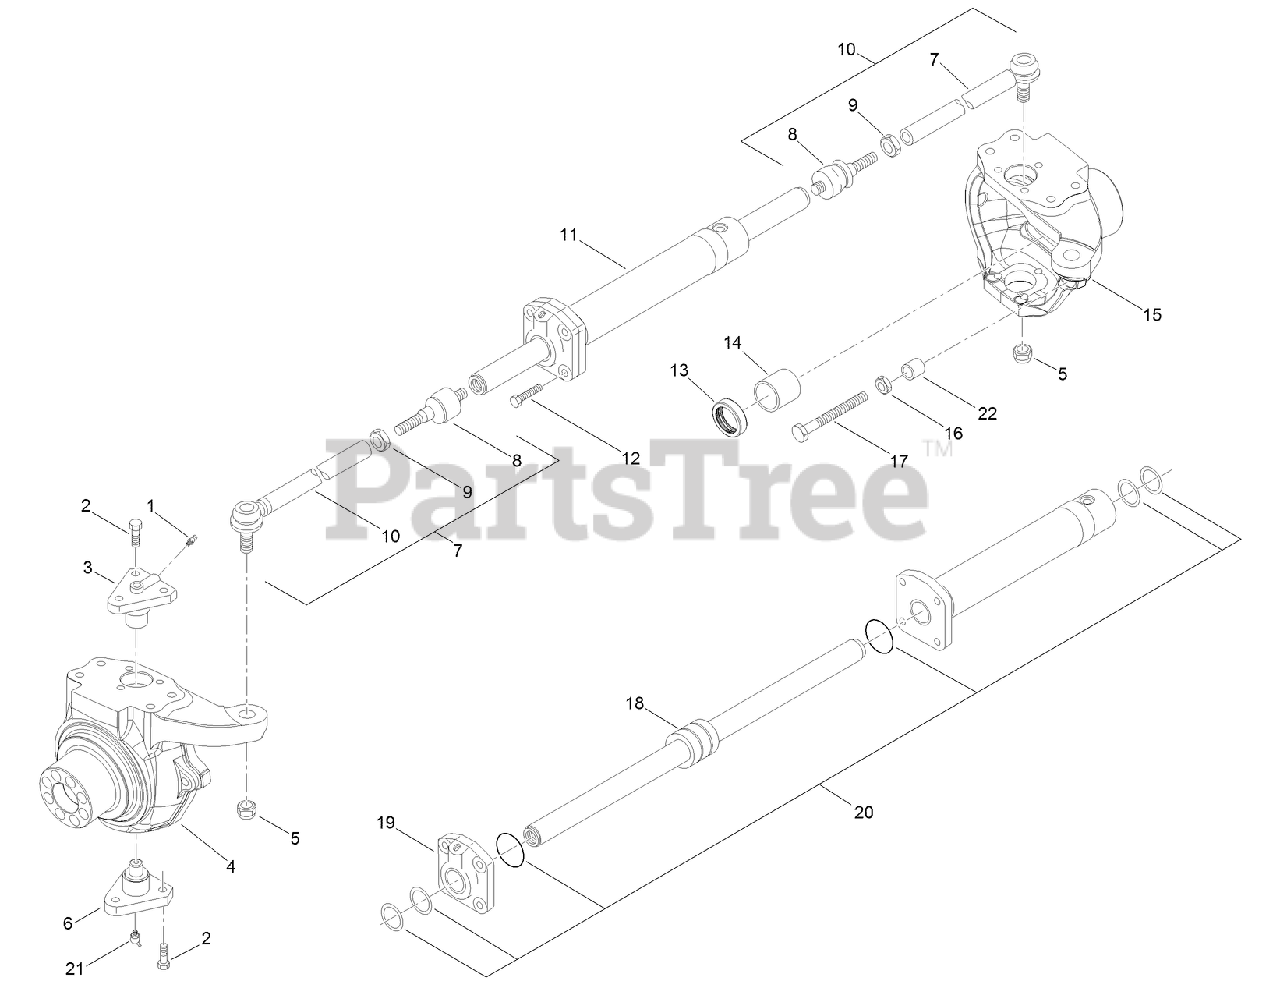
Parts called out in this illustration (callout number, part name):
1	GREASER-NIPPLE
3	PIN-KING
4	LH SWIVEL HOUSING ASM
6	PIN-KING
7	STEERING ARM ASM
8	JOINT-BALL
10	ROD-TIE
11	STEERING CYLINDER ASM
13	SEAL-RING
14	BUSHING
15	RH SWIVEL HOUSING ASM
19	HEAD-CYLINDER
20	OIL SEAL KIT
21	GREASER-NIPPLE
22	BUSHING
